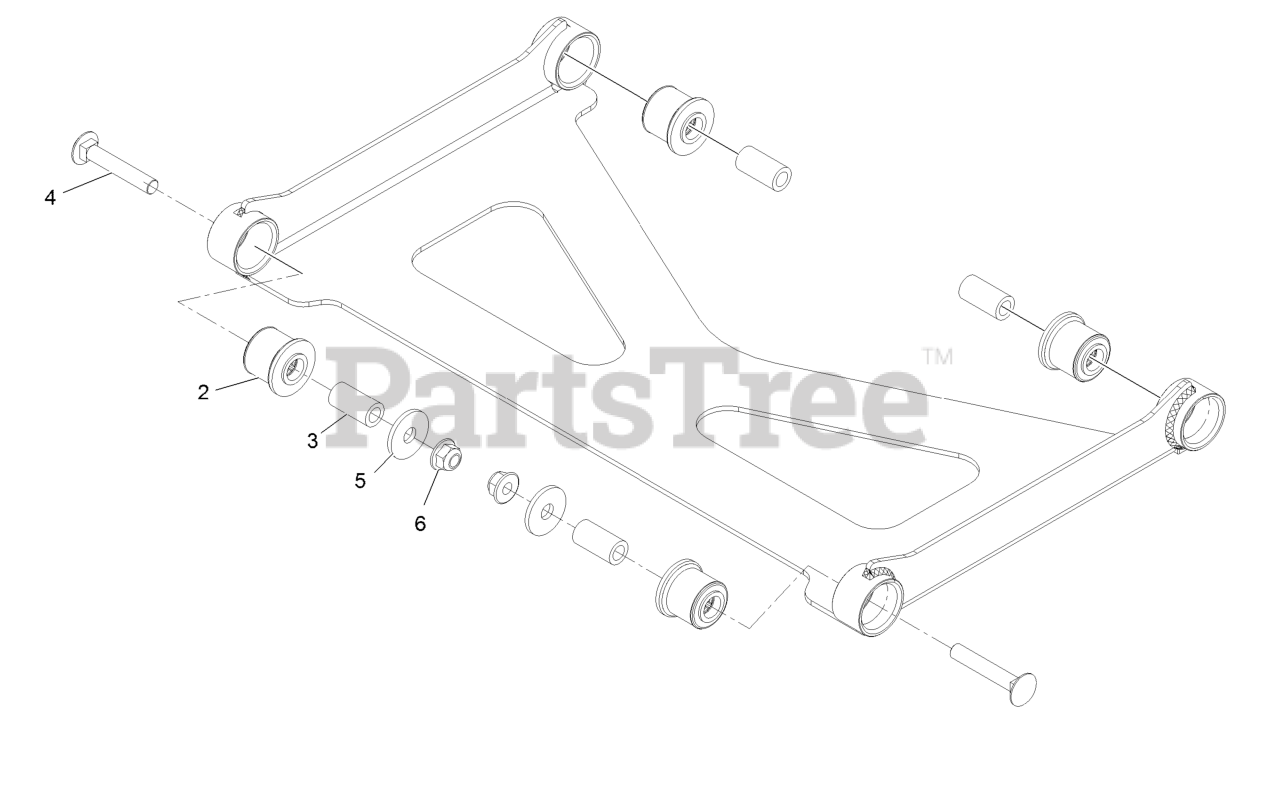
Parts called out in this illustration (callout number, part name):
2	Bushing-Rubber, Suspension
4	Bolt-Carriage 3/8-16 X 2 1/4
5	Washer
6	Nut-Nyloc 3/8-16 Flg
